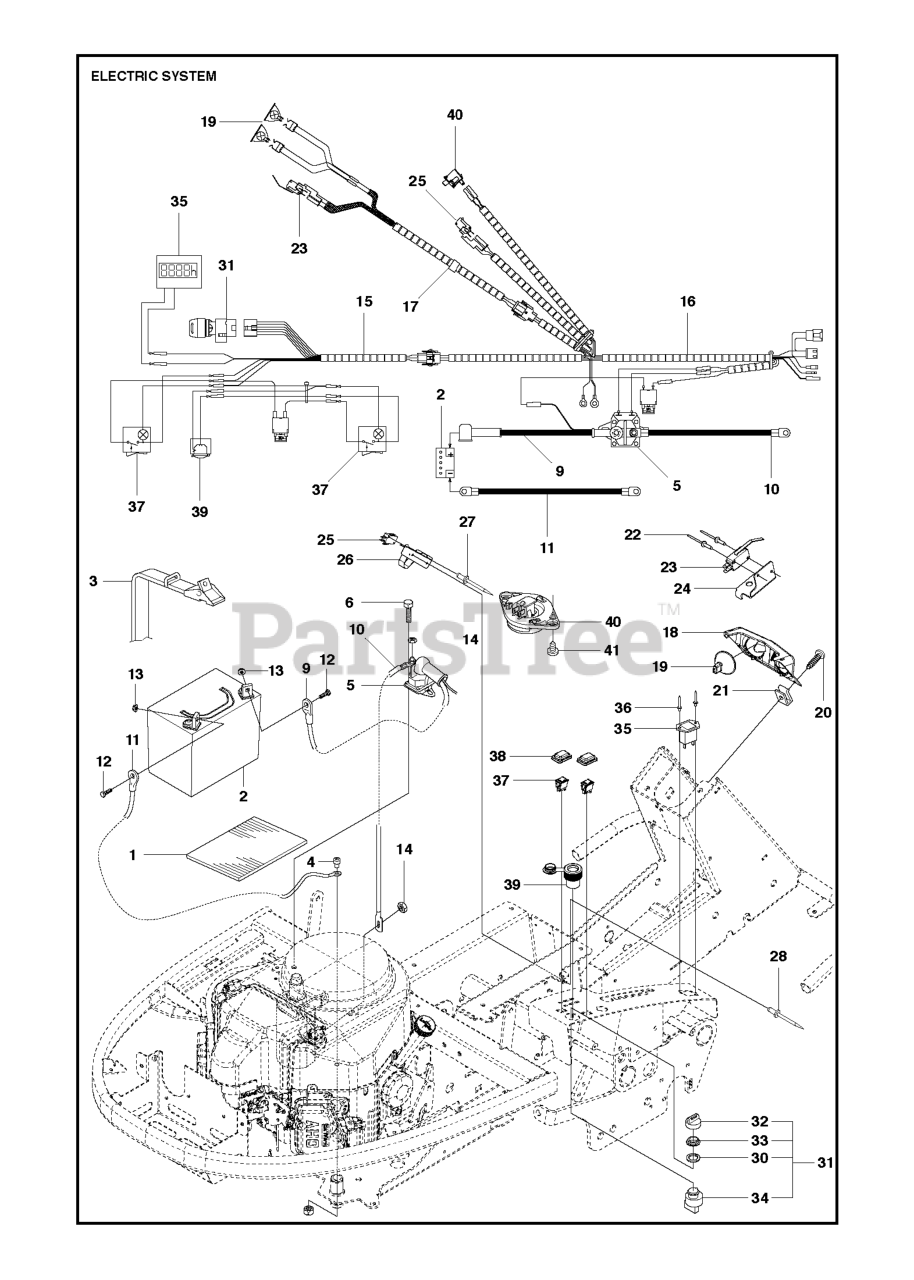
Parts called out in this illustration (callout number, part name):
4	SCREW IHSCM
12	SCREW EHHM
19	LAMP
23	MICRO SWITCH
35	HOUR METER
41	SCREW
